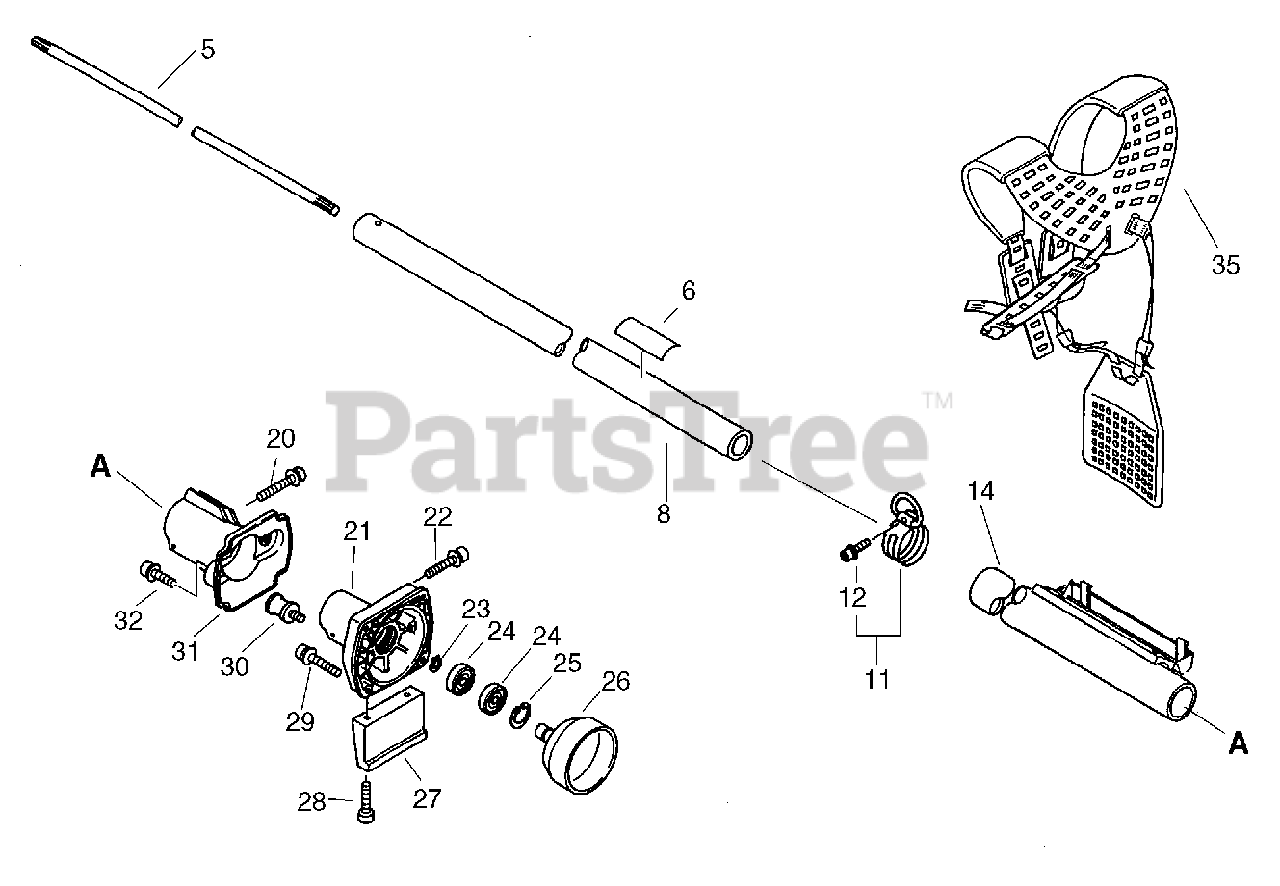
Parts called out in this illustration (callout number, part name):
5	DRIVESHAFT
6	LABEL, CAUTION - ISO
8	PIPE, MAIN
11	HANGER KIT
12	BOLT 5×20
14	PIPE ASSY
20	BOLT M5×35
22	BOLT 5×30
23	RING, RETAINING 15
24	BEARING, BALL 6203
25	RING, SNAP 35
26	DRUM, CLUTCH
28	BOLT 5×20
29	BOLT 5×25
32	BOLT 5×14
35	HARNESS, SHOULDER
